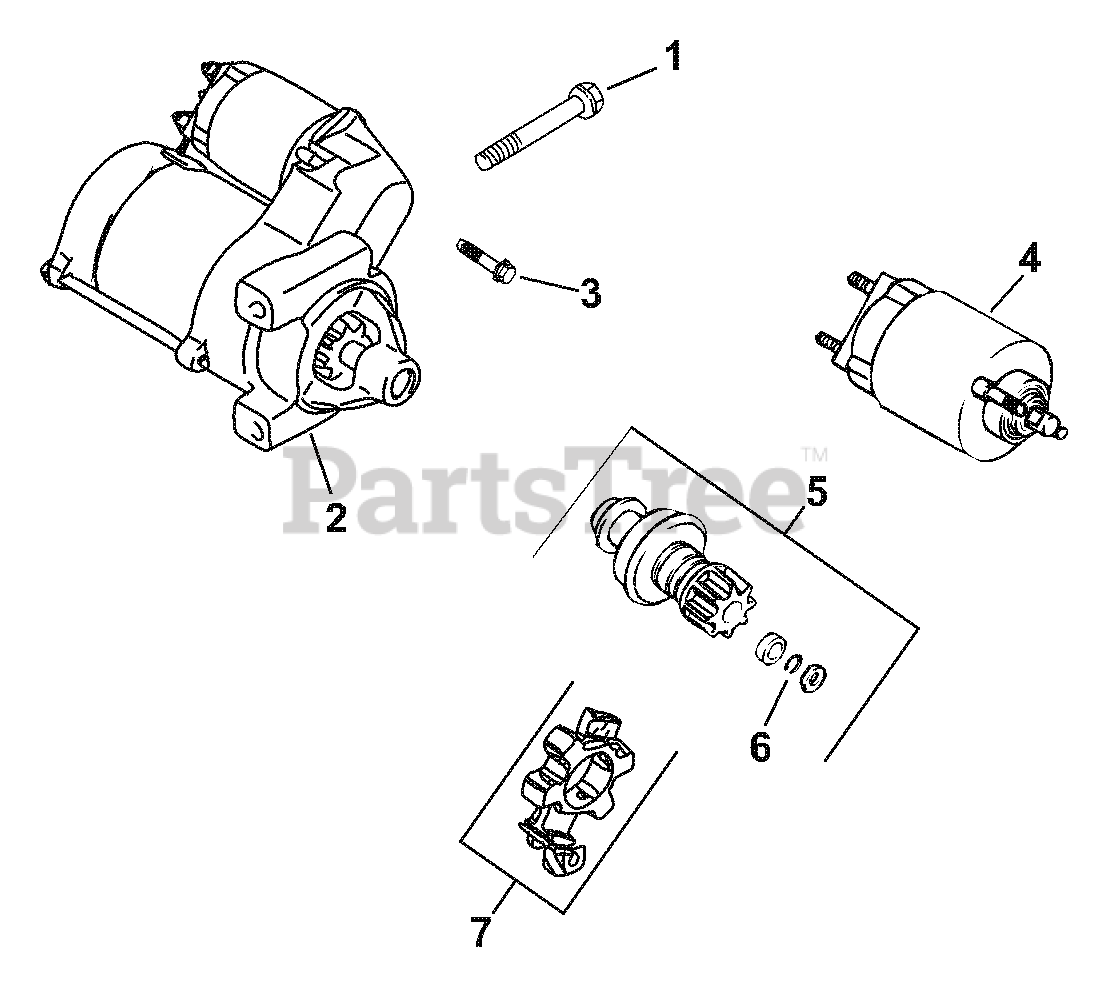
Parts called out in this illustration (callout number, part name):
1	Screw, hex. flange M8x1.25x80
2	Starter, solenoid assembly
3	Screw, external torx hd.
4	Kit, solenoid
5	Kit, starter pinion
